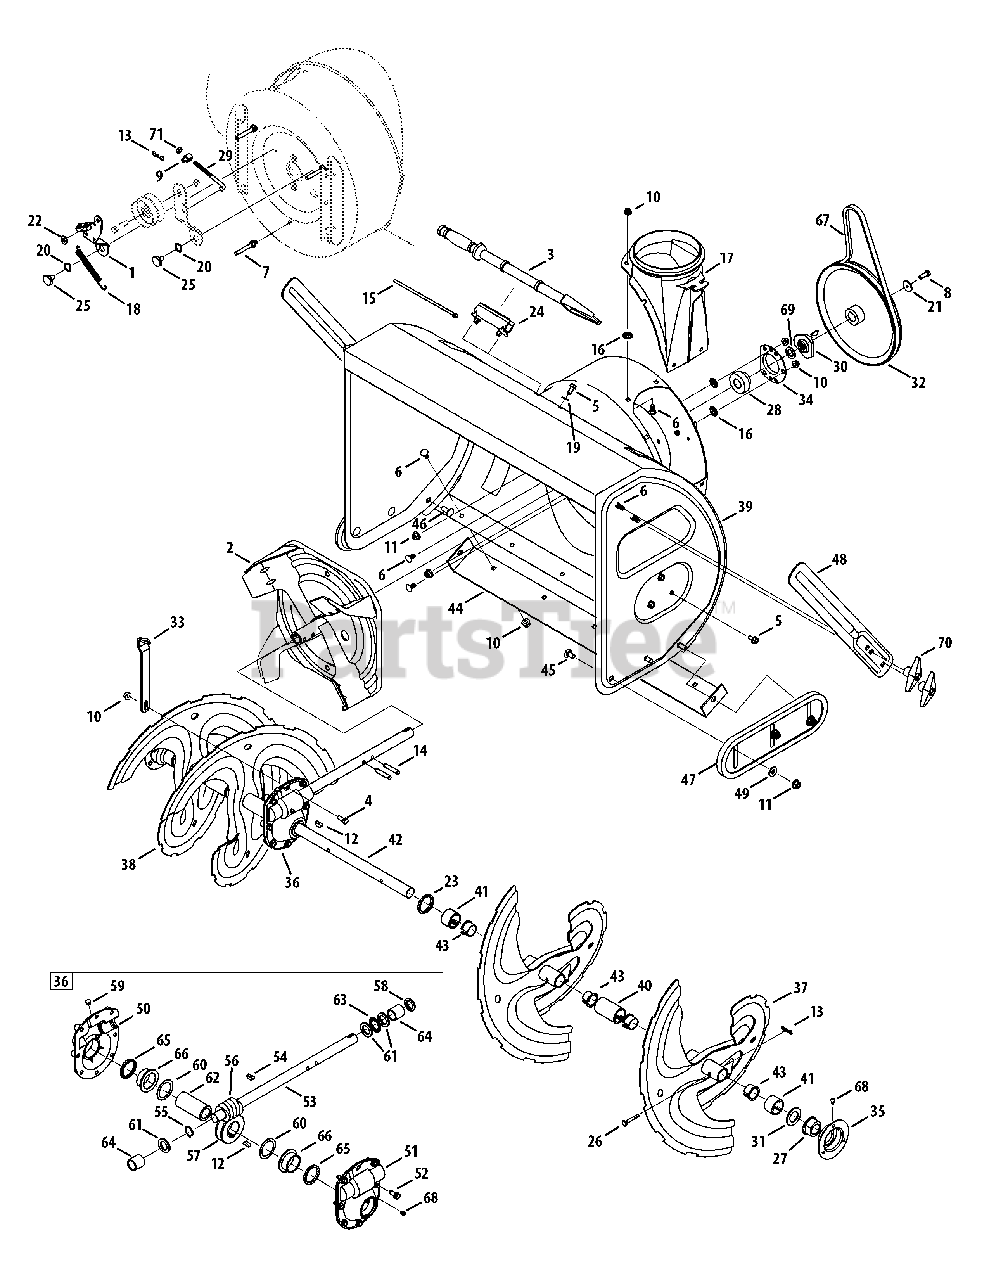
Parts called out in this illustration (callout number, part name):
1	Bracket Assy, Auger Brake
2	Impellar, 16"
3	Tool, Cleanout
4	Scr,Hex Cap, 5/16-18 x 1.00
5	Screw, 5/16-18 x .750
6	Screw, Carriage, 5/16-18 x .75
7	Screw, 5/16-18 x .4300
8	Screw, 5/16-24 x .875
9	Ferrule
10	Nut, Flnge Lk, 5/16-18
11	Nut, Flg Lk, 3/8-16
12	Key, Woodruff,1/4 x 3/4
13	Pin, Bowtie Cotter
14	Pin, Spirol, 5/16 x 1.75
15	Tie, Cable
16	Nut, Push
17	Adapter, Chute, 6"
18	Spring, Extension
19	Washer, .349 x .879 x .063
20	Washer, .625 x .885 x .015
21	Washer, Flat, .34 x 1.50 x .150
22	Washer, .344 x .75 x .12
23	Washer, 1.01 x 1.86 x .06
24	Clip, Mounting
25	Screw, Shoulder, .625 x .17
26	Pin, Shear, .25 x 1.75
27	Bearing, Flange w/Flats
28	Bearing, Self Aligning
29	Rod, Auger Idler
30	Pulley, Adapter, .75 Dia.
31	Spacer, 1.004 x 1.375 x .25
32	Pulley, Auger Drive, 10.0
33	Bracket, Gear Box Support
34	Housing, Bearing
35	Housing, Bearing
36	Gear Box Assembly, Auger
37	Spiral Assy, LH
38	Spiral Assy, RH
39	Housing, Auger - 33"
40	Spacer, 1.0 x 1.5 x 2
41	Spacer, 1.0 x 1.5 x 1
42	Axle, Spiral, 33"
43	Bushing, Flange, 1.051 x 1.16
44	Shave Plate
45	Bolt, Carriage, 3/8-16 x 1.0
46	Bolt, Carriage, 3/8-16 x 1.25
47	Shoe, Skid
48	Drift Cutter
49	Washer, Flat, .385 x .870
50	Hsg Assy Auger RH (Inc. 65 & 66)
51	Hsg Assy Auger LH (Inc. 65 & 66)
52	Screw, LD, 5/16-18 x .750
53	Shf, Drive, Auger
54	Key, Hi Pro, 3/16 x 3/4
55	Ext, Ret, Ring
56	Gear, Worm, Dbl Thread
57	Gear, Worm, LH
58	Seal, Oil
60	Washer, Flat, 1.52 ID x 2.0 OD
61	Washer, Flat, .88 ID x .38 OD
62	Shf, Gear, Worm
63	Brg, Thrust
64	Sleeve
65	Oil Seal
66	Flange Bearing
67	V Belt,4L x 44.60 Lg.
68	Lube Fitting, 3/16 #70
69	Washer, Flat, .78 x 1.49 x .08
70	Wing Knob
71	Jam Nut, 5/16-18
